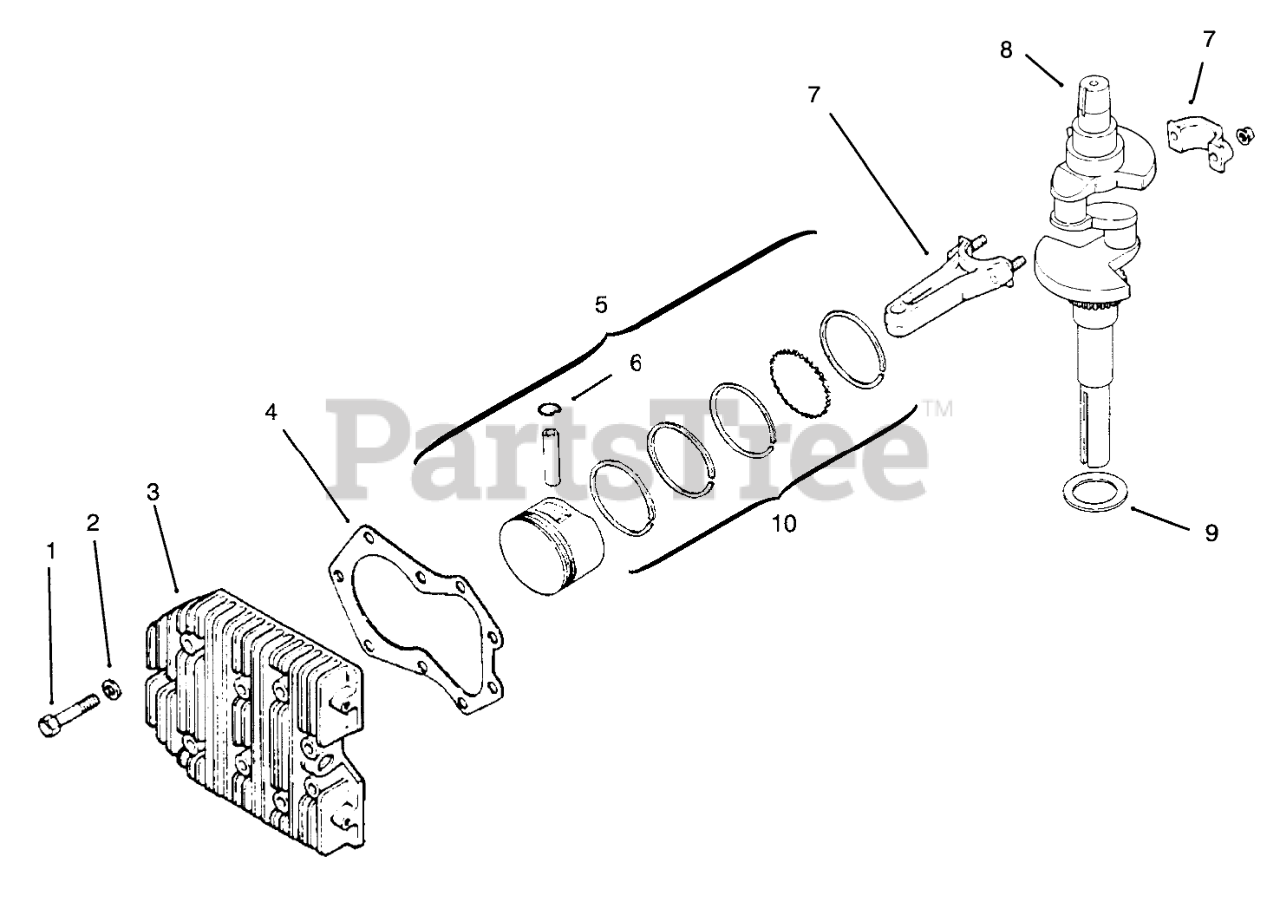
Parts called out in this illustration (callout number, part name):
1	Screw-Hex. Hd.
2	Washer
3	Head-Cylinder
4	Gasket-Head
5	Piston-w/Ring Set (Std.)
6	Retainer, Pin
7	Rod-Connecting (Std.)
8	Crankshaft
9	Washer-.119/.122
10	Ring-Set (Std. & .003)
